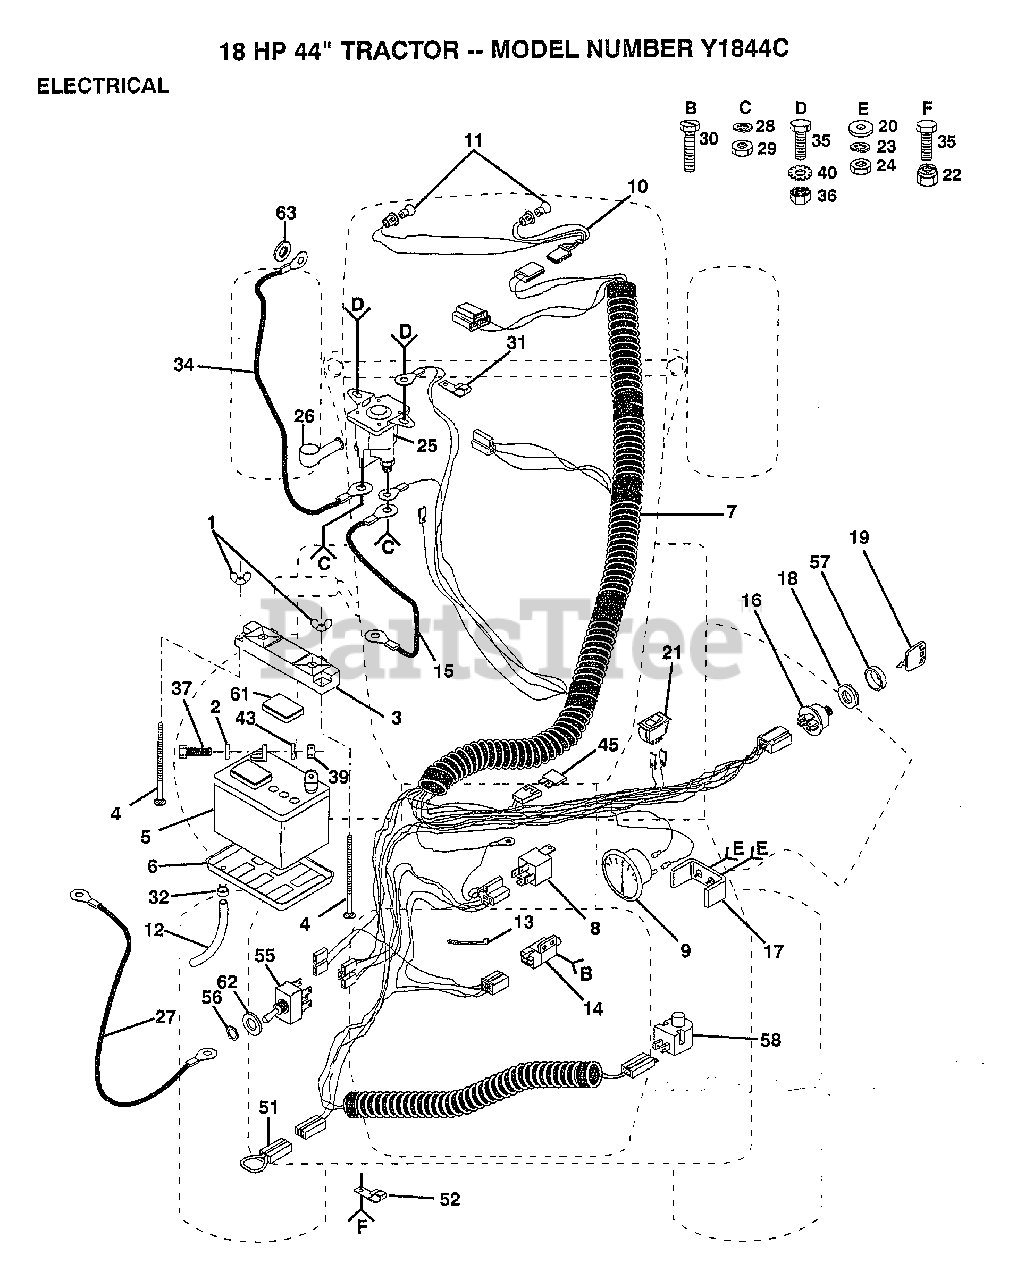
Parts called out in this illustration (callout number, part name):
2	WASHER
4	BOLT
6	"TRAY T, BATTERY"
8	RELAY ASSY T
9	AMMETER T
10	"HARNESS,LIGHT SOC"
11	HEADLAMP BULB
12	"DRAIN TU T, BATT"
13	WIRE TIE
14	SWITCH-INTER. GT
15	CABLE-BATTERY T
16	JOINT CRT
18	NUT IGNITION
19	KEY
20	WASHER
21	SWITCH LT
27	CABLE T
29	NUT
30	SCREW
31	CLIP T
32	HOSE CLAMP T
34	"CABLE T, BATTERY"
35	BOLT
36	NUT
37	BOLT LT
43	LOCKWASHER
45	FUSE HYT
52	CLIPT
56	HEX NUT T
58	SWITCH SEAT
61	"CAP,BATTERY "
62	WASHER
63	LOCKWASHER
